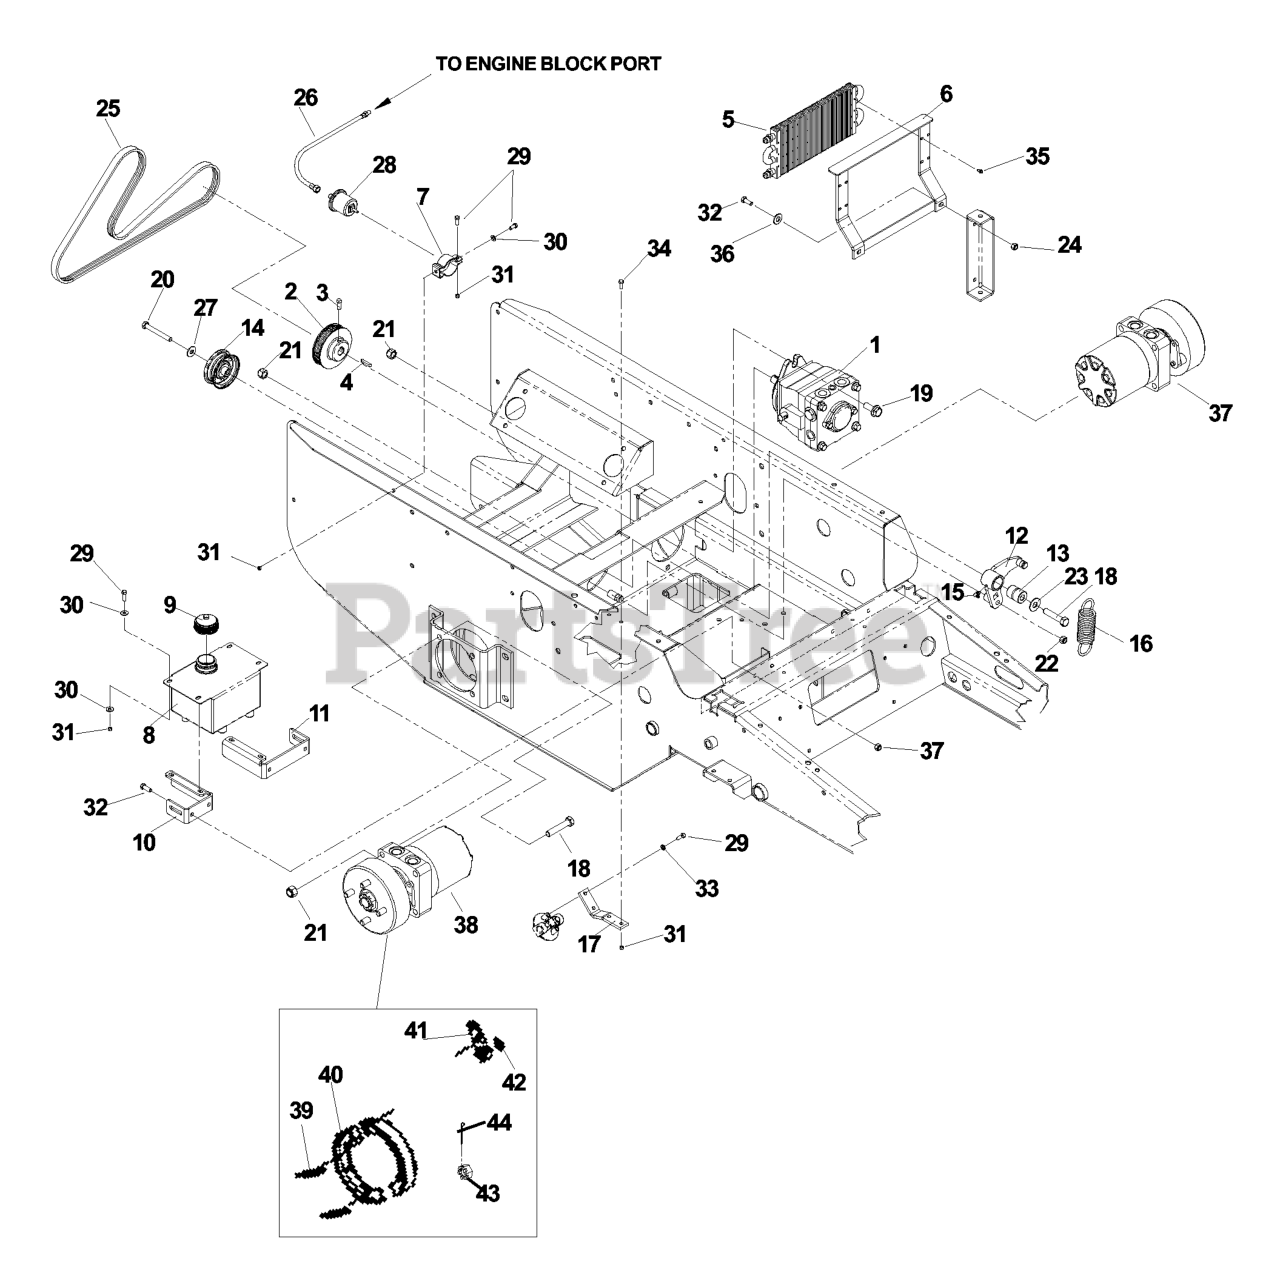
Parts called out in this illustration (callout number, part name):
1	HG_PUMP CCW RH
2	PUMP SHEAVE
3	SCREW, HEAD SET 5/16C X 3/4 SQ
4	KEY, METRIC
6	COOLER WLDMT MT
7	CLAMP-OIL SENDER
8	TANK, OIL = PAINTED
9	HYDRAULIC CAP
10	TANK MOUNT RT
11	TANK MOUNT LT
12	ARM WELDMENT
14	IDLER PULLEY
17	FILTER MOUNT - PAINTED
18	HEX SCREW 1/2-13 X 2.5" GR 5
19	HCS 1/2C X 1 1/4 SERRATED HEAD
20	HCS 3/8C X 3
21	NUT 1/2-13 HEX NYLOC ZD
22	NUT 3/8-16 NYLOC
23	WASHER 1/2 FLAT
24	NUT 5/16 NYLOC
27	WASHER 3/8 SAE FLAT
28	SENDER,OIL PRESS
29	HCS 1/4C X 3/4 HCS
30	WASHER 1/4 FLAT
31	NUT.1/4-20.HEX.NYLOC.ZD
32	HCS 5/16C X 1
33	LOCKWASHER 1/4"
34	HCS 1/4 X 1
35	HSMS #10 X 5/8
36	WASHER 5/16 FLAT
37	WHEEL MTR ASM
38	WHEEL MTR ASM, RT
39	RETURN SPRING
43	CASTLE-NUT
44	COTTER PIN
